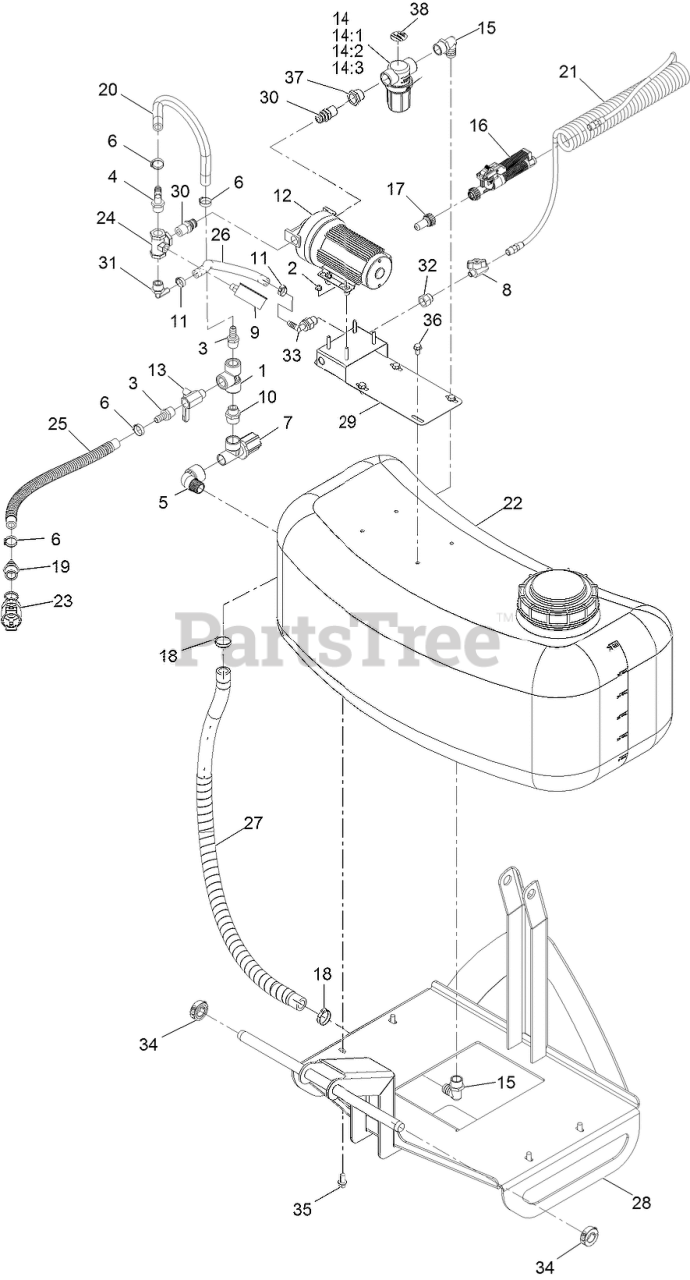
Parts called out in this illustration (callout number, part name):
3	FITTING-HOSEBARB
4	FITTING-ELBOW, HOSEBARB
5	ELBOW-90DEG
6	CLAMP-OETIKER, 167
7	VALVE-THROTTLE
8	VALVE-CHROME, 1/4
9	GAUGE
10	FITTING-NIPPLE
11	CLAMP-OETIKER, 167
12	PUMP-5.0 GPM
13	VALVE-CHROME, 1/2
14	STRAINER-INLINE
14:1	BOWL-STRAINER
14:2	GASKET-HEAD, LINE STRAINE
14:3	Screen-Strainer, 50 Mesh
15	FITTING-ELBOW, 90
16	GUN-SPRAY, SPOT
17	TIP-SPRAY, #12 SPOT
18	Clamp-Oetiker, 167
19	FITTING-STRAIGHT
20	HOSE-SPRAY
21	HOSE-COILED, 15 FT
22	ASM-TANK, 30 GAL
23	COUPLER-FEMALE
24	FITTING-CROSS
25	Hose-Spray, Wrapped
26	Hose-Spray
27	Hose-Spray, Wrapped
28	BASE-30 GAL ATTACH
29	PUMP MOUNT, 30 GALLON ATT
30	PUMP FTG X 1/2MPT FQ5MS-1
31	1/2'MPT X 3/8' HB 90\N3EL
32	OUTLET ADAPTER\N3NF1614
33	BOOM ELBOWS\N3NTL38
34	Collar-Shaft, Split, Cz
35	Screw-HH Flg 3/8-16 X 3/4
36	SCREW-HHF
37	REDUCER-BUSHING, PLASTIC
38	DECAL-CAP, STRAINER
